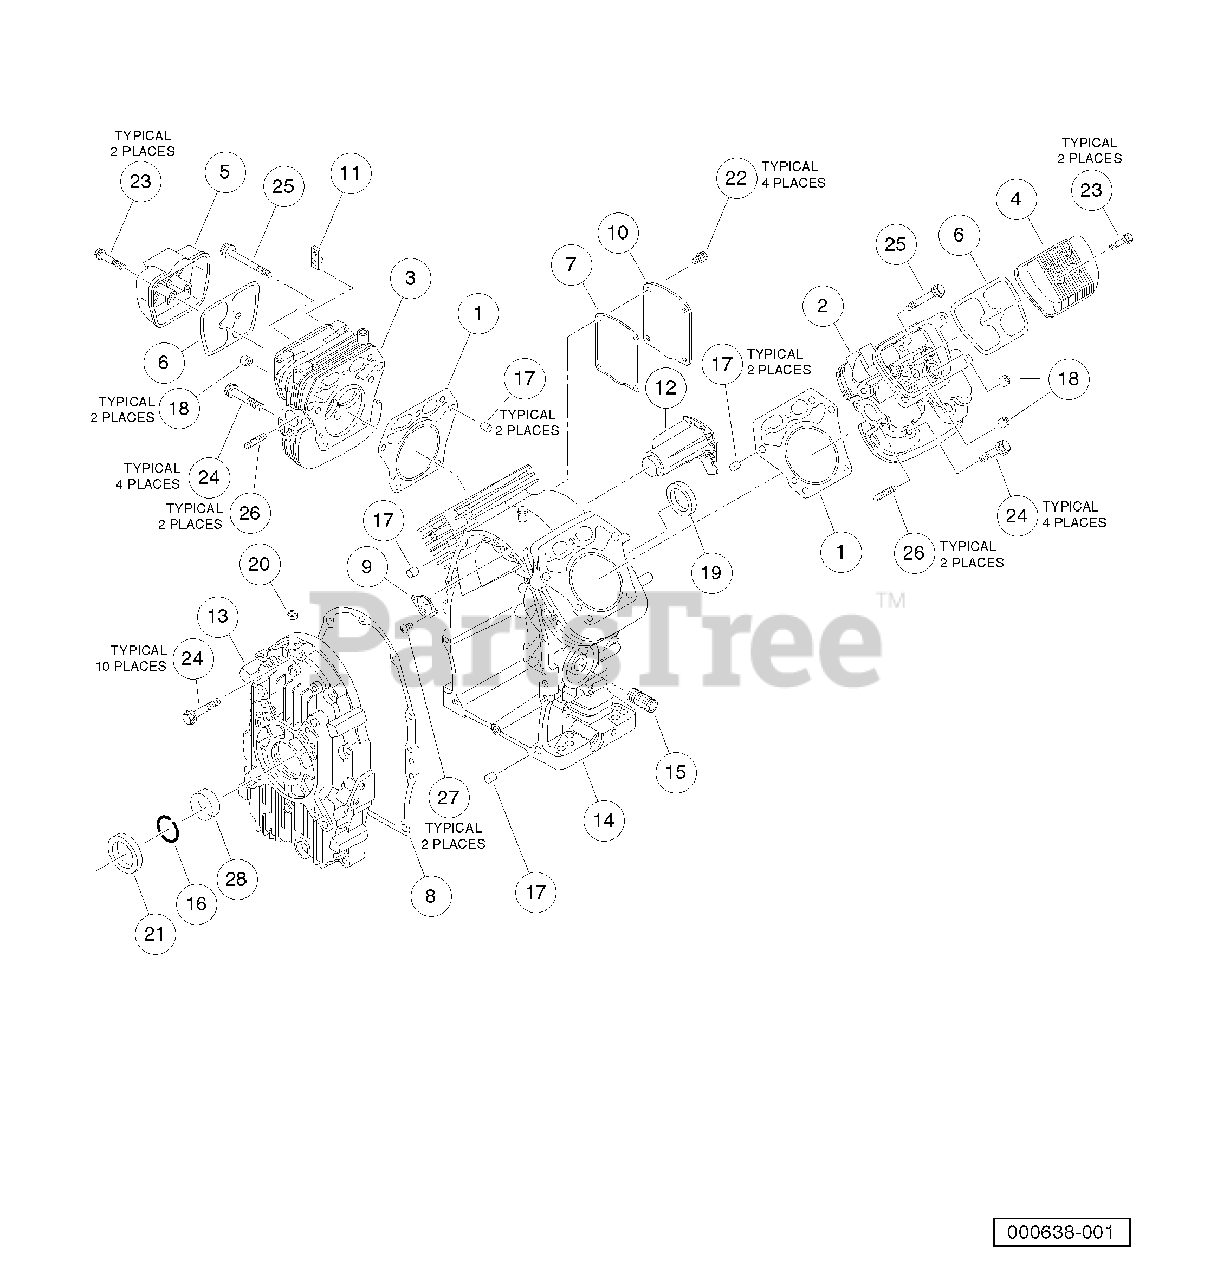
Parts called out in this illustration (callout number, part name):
1	Gasket, Head, Cyl, Fh
2	Head, Cyld 1, Fh
3	Head, Cyld 2, Fh
4	Cover, Rocker, Cyld 1, Fh
5	Cover, Rocker, Cyld 2, Fh
6	Gasket, Rocker, Cover, FH
7	Gasket, Breather, Fh
8	Gasket, Cover, Crank, Fh
9	Valve, Assy, Reed, Fh
10	Cover, Crkcase, Comp, Fh
11	Pipe, Head, Comp, Clyd, Fh
12	Pipe, Crkcase, Comp, Fh
13	Cover, Crankcase, Fh
14	Crankcase, Comp, Fh
15	Nipple, Oil Filter, Fh
16	Ring, Snap, Fh
17	Pin, Head, Fh
18	Seal, Oil, Valve, Fh
19	Seal, Oil, Crank, Rear, Fh
20	Seal, Oil, Governor, Fh
21	Seal, Oil, Crank, Front, Fh
22	Bolt, Flg, M6 X 1.0 X 12
23	Bolt, Flg, M6 X 1.0 X 40
24	Bolt, Flg, M8 X 1.25 X 50
25	Bolt, Flg, M8 X 1.25 X 75
26	Stud, M8 X 1.25, Exhaust, Fh
27	Screw, Pan, Governor, Fh
28	Bushing, Main, Fh
